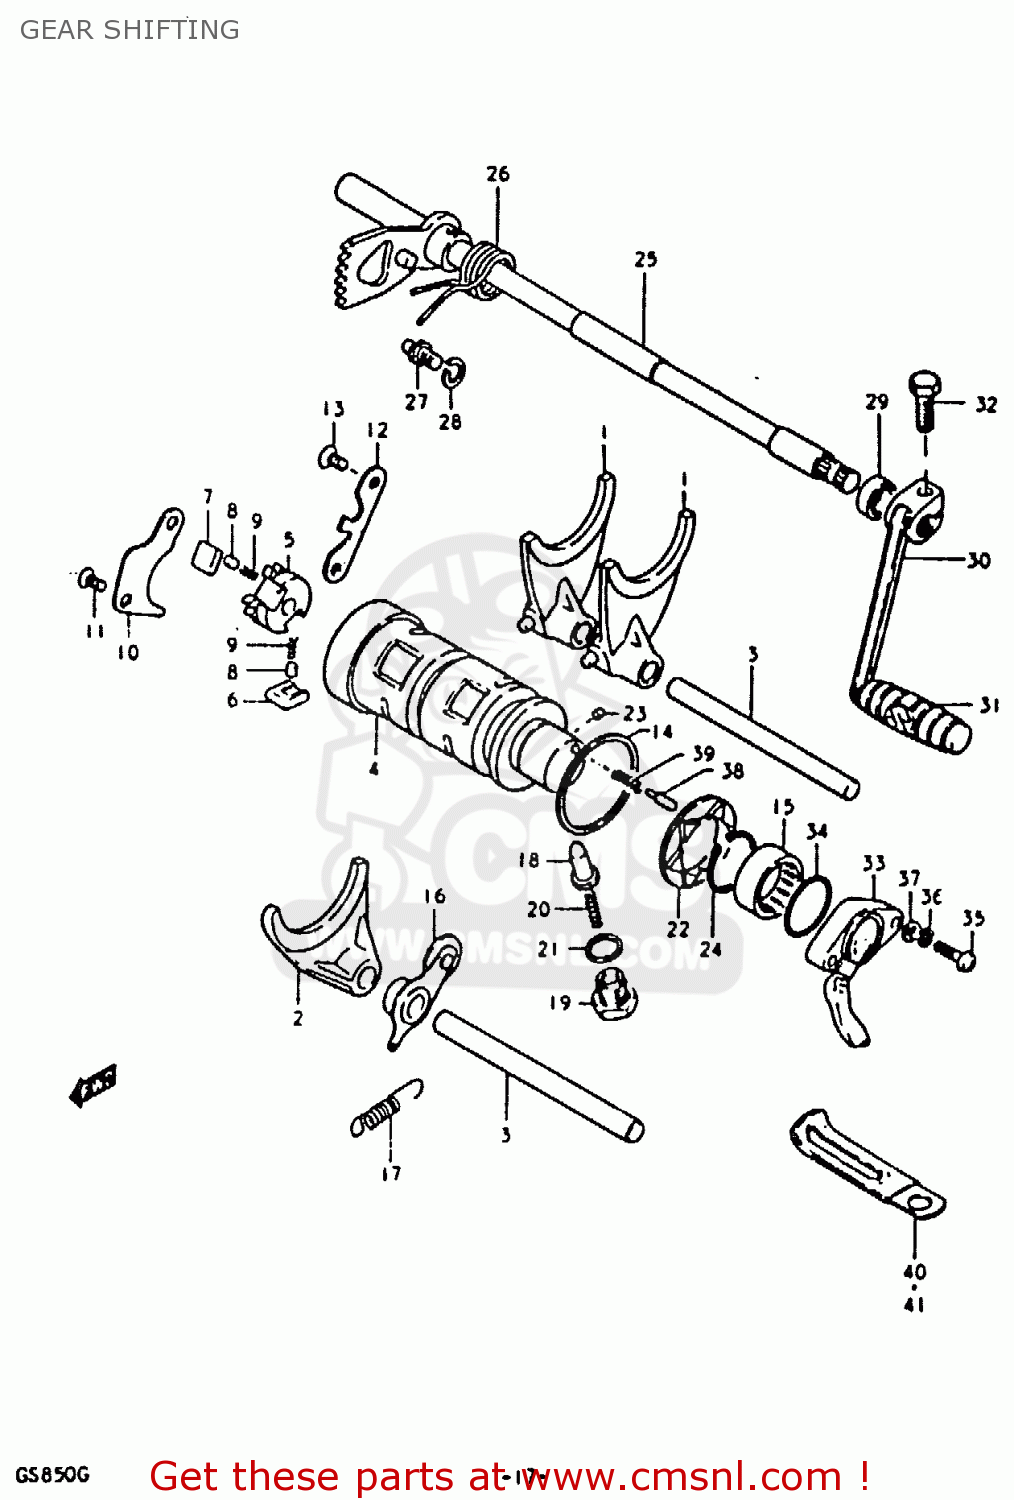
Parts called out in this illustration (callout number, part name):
1	FORK,GEAR SHIFT NO.1
2	FORK,GEAR SHIFT NO.3
3	SHAFT,GEAR SHIFT FORK
4	CAM,GEAR SHIFT
5	RETAINER,GEAR SHIFT CAM
6	PAWL,GEAR SHIFT NO.1
7	PAWL,GEAR SHIFT NO.2
8	PIN(5X8)
9	SPRING
10	LIFTER,GEAR SHIFT PAWL
11	SCREW
12	GUIDE,GEAR SHIFT CAM
13	SCREW
14	WASHER(40X45X1)
15	BEARING(25X32X12)
16	STOPPER,GEAR SHIFTING
17	SPRING
18	STOPPER,GEAR SHIFT CAM NO.2
19	HOLDER,GEAR SHIFT CAM STOP SPR
20	SPRING
21	GASKET(14X19.2X2) (NAS)
22	PLATE,GEAR SHIFT CAM STOPPER
23	PIN 4X6
24	CIRCLIP
25	SHAFT,GEAR SHIFT
26	SPRING
27	STOPPER,GEAR SHIFT CAM
28	WASHER
29	OIL SEAL
30	LEVER ASSEMBLY,GEAR SHIFTING
31	RUBBER,GEAR SHIFT PEDAL
32	BOLT
33	BASE ASSEMBLY,NEUTRAL SWITCH TERMINAL
34	O-RING (D:2.4 ID:26.2)
35	SCREW 5X20
36	LOCK WASHER
37	WASHER
38	PIN(5X15.5)
39	SPRING
40	CLAMP L:35
41	CLAMP
